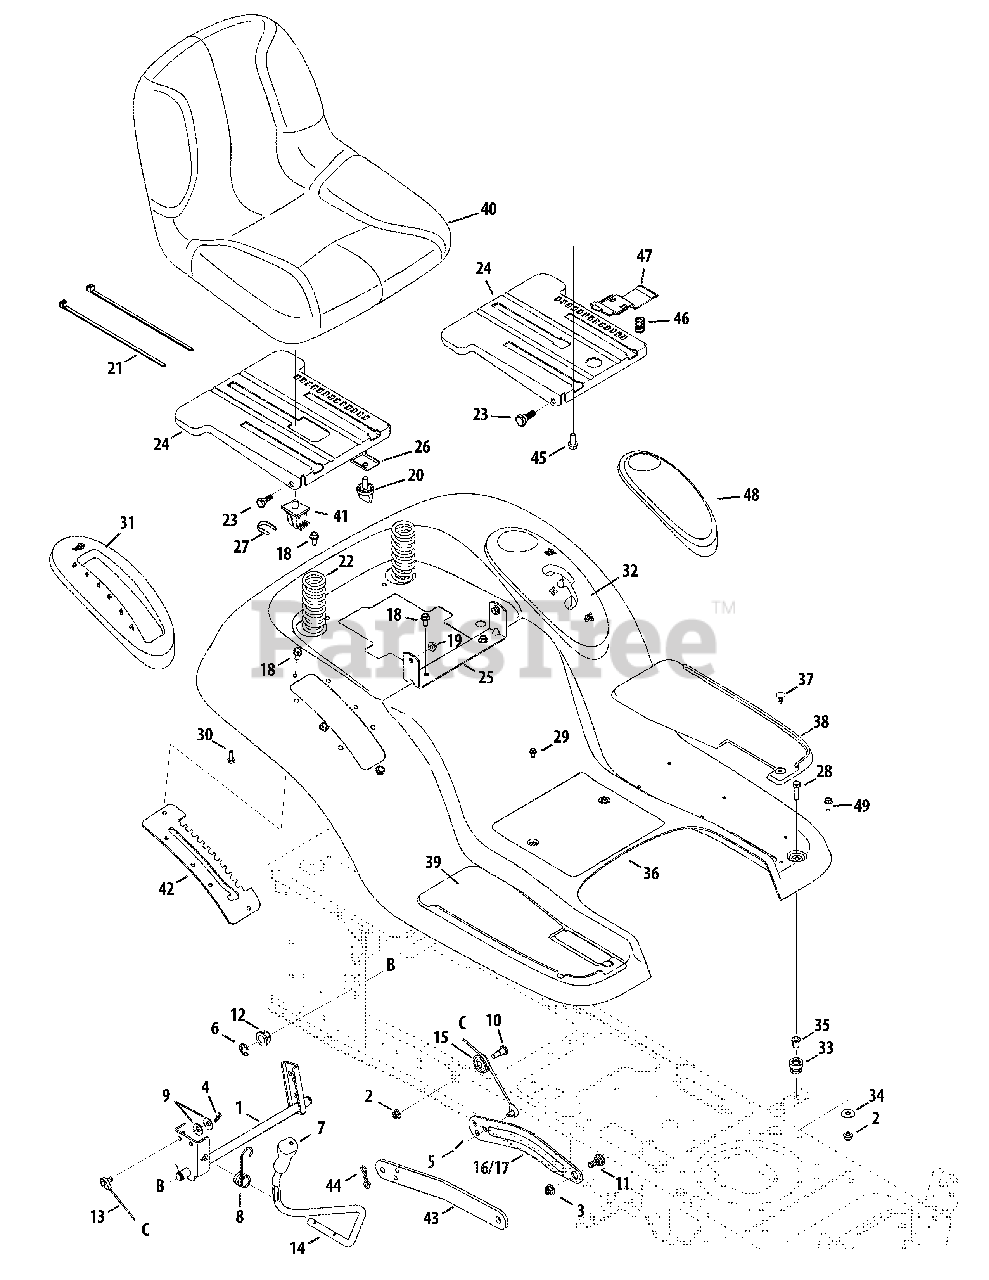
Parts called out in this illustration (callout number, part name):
1	Lift Shaft Ass’y
2	Flange Locknut 5/16-18 Gr. F, Nylon
3	Flange Lock-Nut 3/8-16 Gr. F Nylon
4	Int. Cotter Pin .072 x 1.13" Lg.
5	Bow-Tie Cotter Pin
6	E-ring .625 Shaft
7	Handle Grip
8	Torsion Spring
9	Cupped Washer .375 ID x .870 OD x .063
10	Shoulder Scr. .437 Dia x .47
11	Shoulder Screw .500 x .25 (42")
11	Shoulder Bolt 3/8-16 x .625 (46")
12	Hex Flange Bearing .630 ID
13	Lift Cable, 16.16
14	Lift Handle
15	Roller Pulley
16	Lift Arm RH
17	Lift Arm LH
18	Hex Wash Hd. Tapp Scr. 5/16-18 x .75
19	Hex Flange L-Nut 5/16-18
21	Cable Tie
22	Compression Spring 1.71 x 3.735 x .238
23	Shoulder Screw
24	Seat Mounting Bracket
25	Seat Pivot Bracket
26	Seat Bracket, Knob adjustment
27	Switch Retaining Clip
28	Hex Bolt 5/16-18 x 1.25
29	Hex Wash S-Tapp Scr 1/4-20 x .50
30	Hex Tapp Scr 1/4 x .75" Lg.
31	Lift Lever Cover
32	Shift Lever Cover
33	Grommet .4375 ID x .75
34	Flat Washer .344 ID x 1.0
35	Flange Spacer .3125 x .4375 x .625
37	Foot Pad Clips
38	Foot Pad LH
39	Foot Pad RH
40	Seat, High Back
41	Seat Switch
42	Lift Bracket 6 positions
42	Lift Bracket 12 positions
43	Lift Link (46")
44	Bow-Tie Cotter Pin (46")
